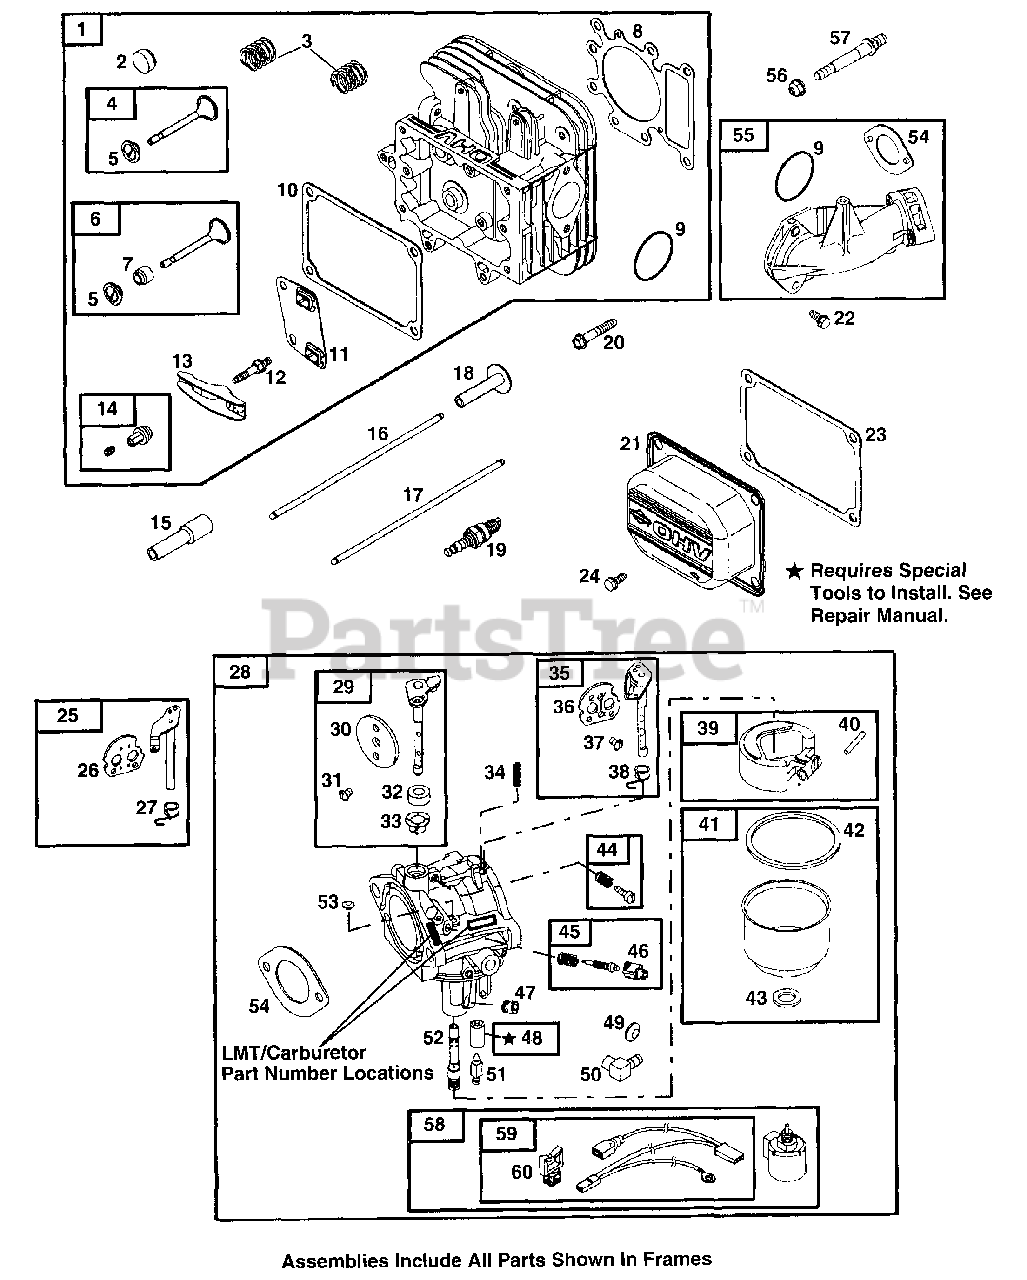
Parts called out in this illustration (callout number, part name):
1	Cylinder Head
3	Valve Spring
4	Exhaust Valve
5	Valve Retainer
6	Intake Valve
7	Valve Seal
8	Cylinder Head Gasket
9	O-Ring Seal (Intake Manifold)
10	Rocker Cover Gasket
11	Push Rod Guide
12	Stud (Rocker Arm)
13	Rocker Arm
14	Rocker Arm Adjuster
15	Sparkplug Boot
16	Pushrod (Intake)
17	Pushrod (Exhaust)
18	Valve Tappet
19	Sparkplug
20	Screw (Cylinder Head)
21	Rocker Arm Cover
22	Screw (Intake Manifold)
23	Rocker Cover Gasket
24	Screw (Rocker Arm Cover)
25	Choke Shaft Kit
26	Choke Valve
27	Spring/Seal Assy (Choke A Matic)
28	Carburetor
29	Throttle Shaft Kit
30	Throttle Valve
31	Screw (Throttle Valve)
32	Throttle Shaft Seal
33	Throttle Shaft Bushing
34	Screw (Drive Cap)
35	Choke Shaft Kit
36	Choke Valve
37	Screw (Choke Valve)
38	Spring/Seal Assy
39	Carburetor Float
40	Float Hinge Pin
41	Float Bowl
42	Float Bowl Gasket
43	Sealing Washer
44	Idle Speed Kit
45	Idle Mixture Kit
46	Limiter Cap
47	Main Jet (Standard)
48	Inlet Seat (Gravity Feed)
49	Welch Plug
50	Hose Connector
51	Float Needle Valve
52	Carburetor Nozzle
53	Welch Plug
54	Intake Gasket
55	Intake Manifold
56	Nut (Carburetor)
57	Stud (Carburetor)
58	Fuel Solenoid
59	Wiring Harness
